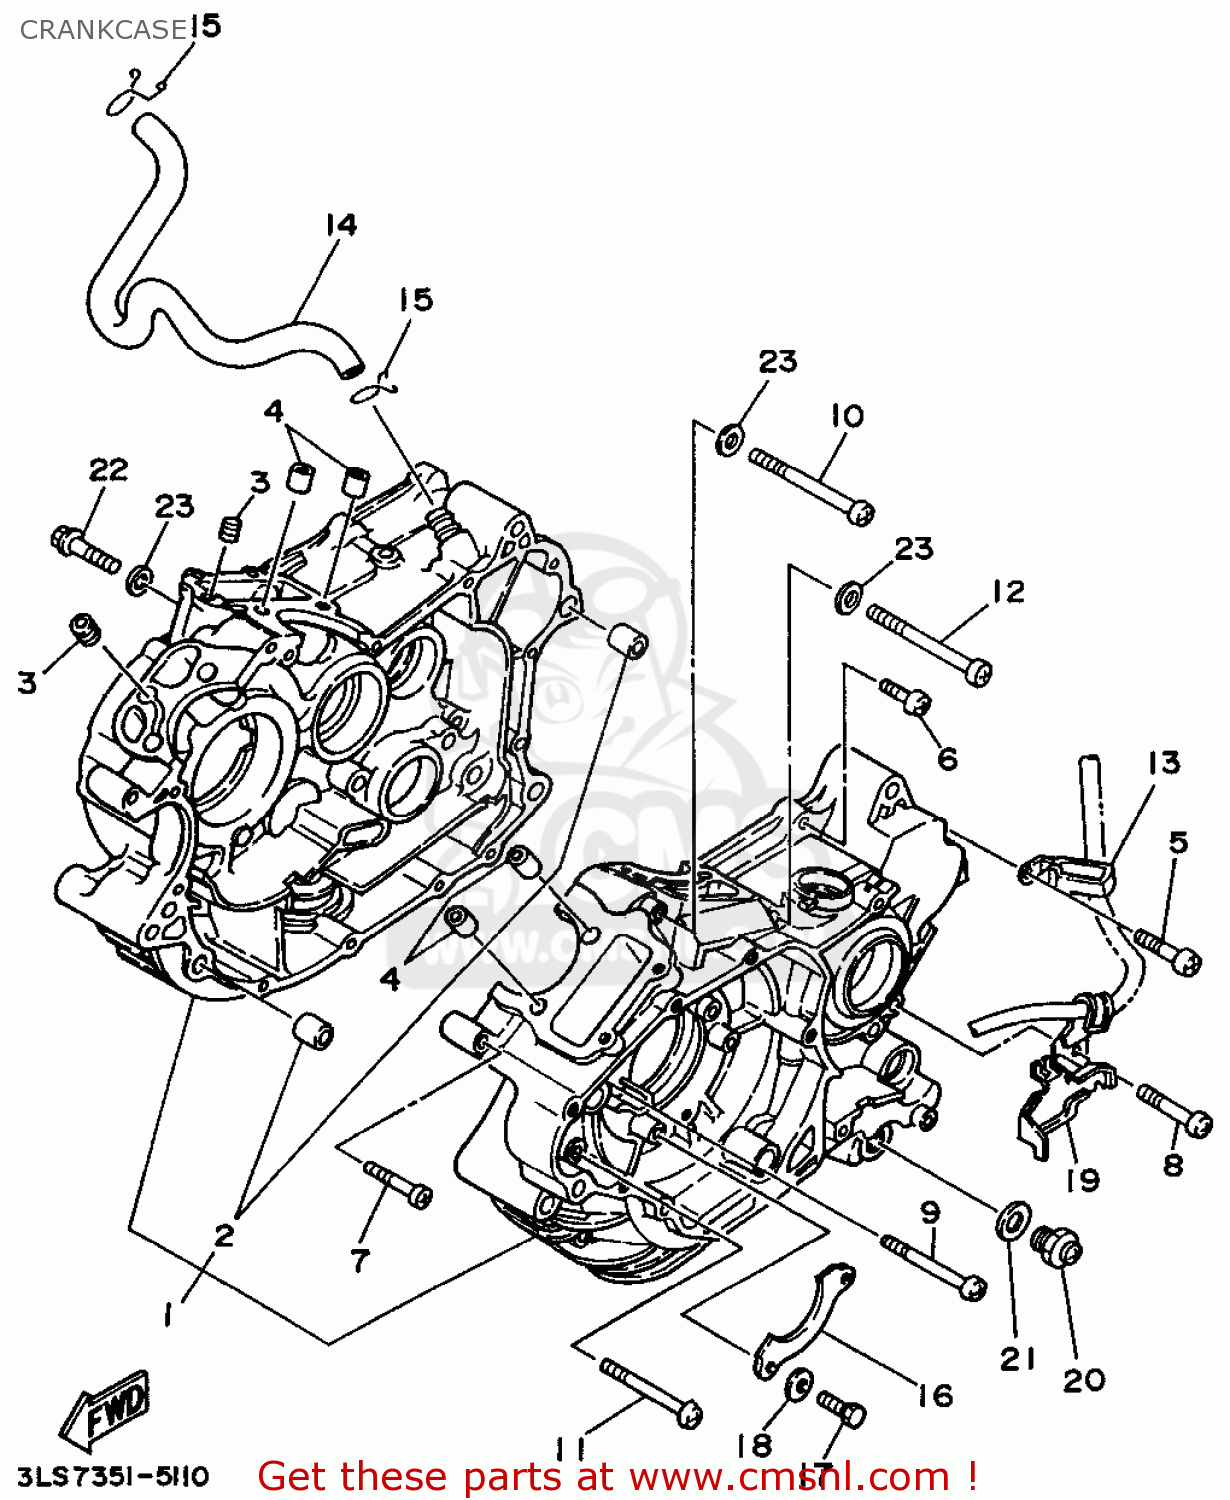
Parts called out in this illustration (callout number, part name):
1	CRANKCASE ASSY
2	P1N, DOWEL
3	NOZZLE 1
4	P1N, DOWEL
5	SCREW, PAN HEAD(4MY)
6	SCREW, PAN HEAD(3DN)
7	SCREW, PAN HEAD(3DN)
8	SCREW, PAN
9	SCREW, PAN HEAD
10	SCREW, PAN HEAD(3DN)
11	SCREW, PAN
12	SCREW, PAN HEAD(3DN)
13	CLAMP(51Y)
14	PIPE, BREATHER 1
15	CLIP (371)
16	PLATE
17	BOLT(6U1)
18	WASHER(6TA)
19	CLAMP (3Y6)
20	PLUG
21	GASKET (NAS)
22	SCREW (33N)
23	GASKET 256113960000 (NAS)
